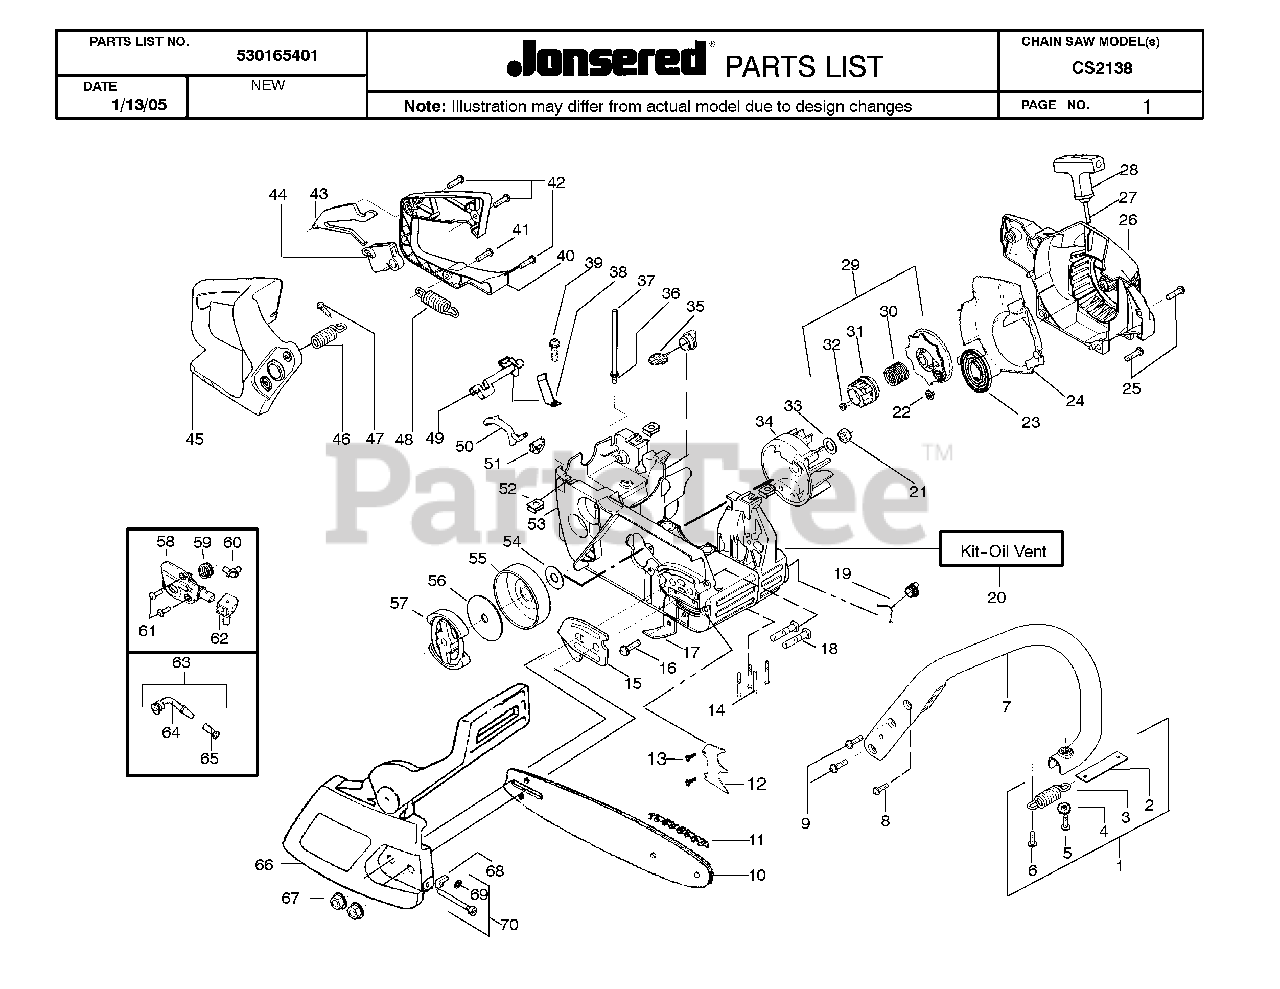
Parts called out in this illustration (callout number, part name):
2	STRAP
3	SPRING ISOLATOR
4	WASHER
7	HANDLE
12	SPIKE 36/41
17	CHAIN CATCHER 36/41
19	OIL TANK CAP
20	KIT-OIL CHECK VALVE
21	NUT-FLYWHEEL
22	SCREW SEMS TOOTHED WASHER
24	AIR BAFFLE
25	SCREW,STRTR CVR 36/41
28	HANDLE STARTER
29	KIT EPS STARTER
30	SPRING EPS
31	HUB STARTER EPS
32	SCREW SHOULDER
33	WASHER-FLYWHEEL
35	TANK CAP
36	FUEL LINE FITTING
38	SPRING-SWITCH
39	SCREW 8-16 X 9/16 (PLAS
41	SCREW-10-14 X 13/16 (PL
42	SCREW,FRONT HBAR 36/41
43	THROTTLE LOCK
44	THROTTLE TRIGGER
46	SPRING
48	SPRING ISOLATOR
49	LEVER-SWITCH
50	LEVER-CHOKE
54	DUST COVER 36/41
55	CLUTCH DRUM ASSY
56	FRICTION DISC,CLUTCH 36/41
57	CLUTCH ASSEMBLY
59	WORM GEAR
64	PICK-UP OILER
65	SCREEN/FILTER
68	ADJUST PIN,BAR 36/41
